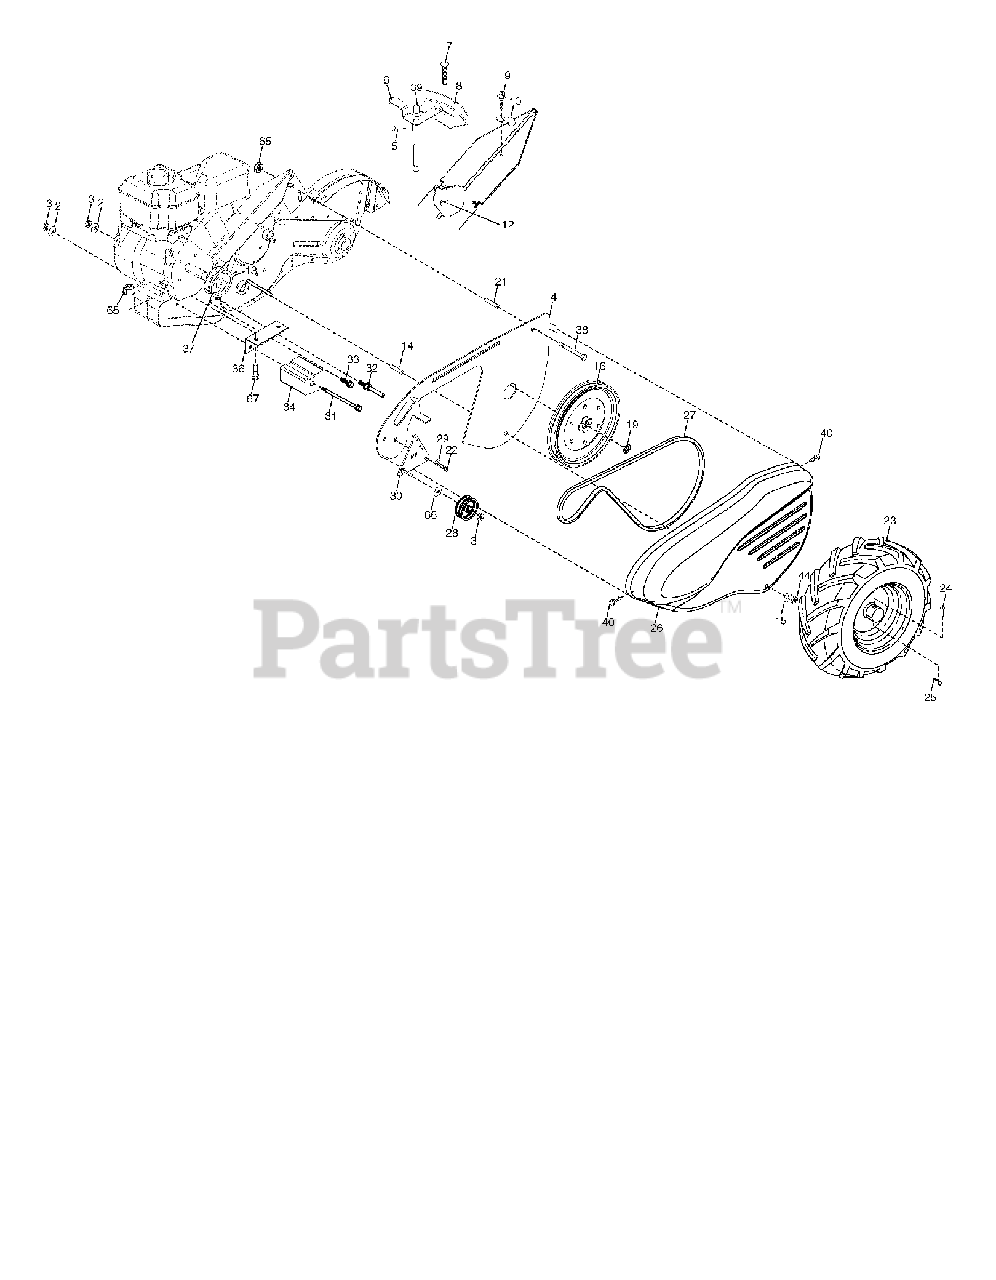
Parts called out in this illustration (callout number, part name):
3	NUT.HEX.3/8-16UNC
4	SHIELD.INNER.BELT.GUARD.RT
5	PIN.SPIROL.FLARED
6	LEVER ASM CRT
8	PANEL.INDICATOR.SHIFT.BLACK
10	CONDUIT CLIP T
12	NUT
13	SET SCREW
14	SPACER-SPLIT.327 X .42
15	WASHER
16	SHEAVE, TRANSMISSION
19	RETAINING RING LT
21	SPACER CRT
23	TIRE.CHV.13X5-6
24	RIVET,DRILLED
27	V-BELT
28	PULLEY-IDLER TI
29	KLIP RING
30	BRACKET.ASM.IDLER.BLACK
31	BOLT CRT
32	SHIFT ARM CRT
33	BOLT
34	COUNTERWEIGHT, RH
35	BOLT
36	BRACKET LH CRT
37	ENGINE PULLEY
39	CAP.PLUNGER.BLACK
40	SCREW.HEX.WSH.SLT.#10-24X.50
44	NUT.71038.31-18.HEX.NYLOCK
65	LOCKNUT-FLANGE 5/16-18
66	WASHER
67	BOLT
